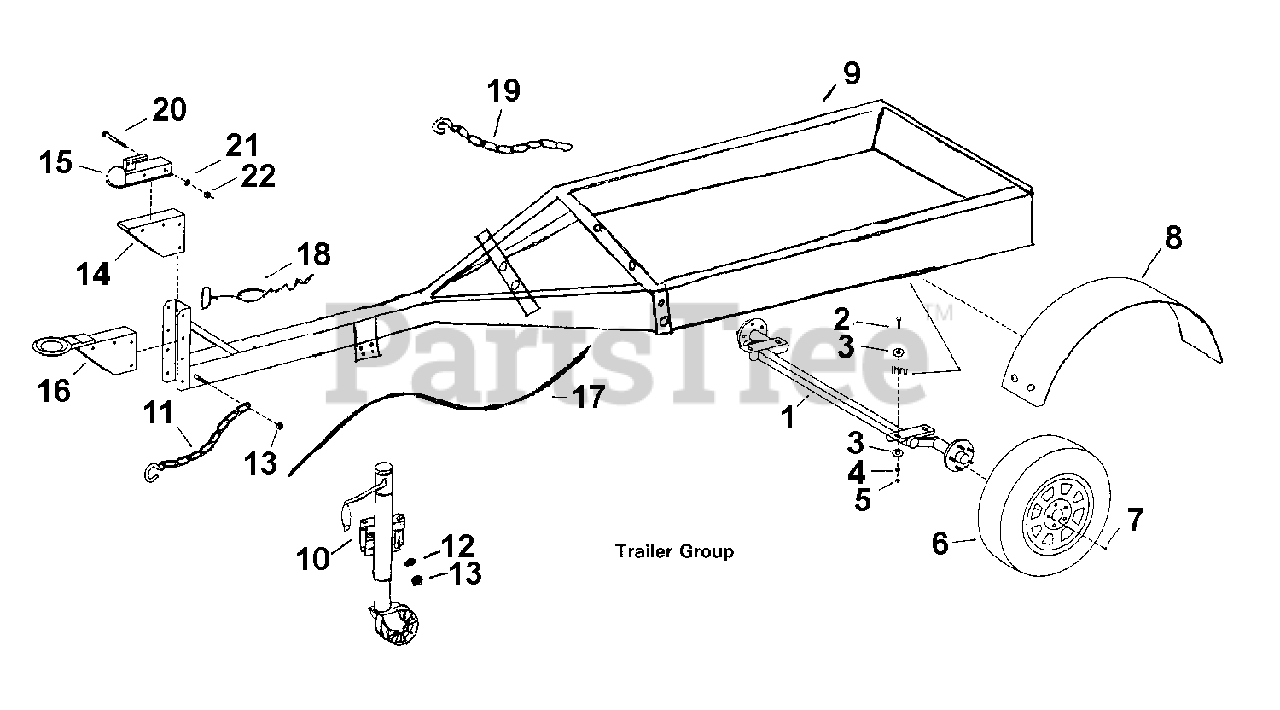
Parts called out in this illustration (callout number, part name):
1	Torflex Axle
2	1/2-13x1-1/4 Hex Bolt
3	1/2 Flat Washer
4	1/2 Lock Washer
5	1/2-13 Hex End Lock Nut
6	Tires 700x15
8	Fender R.H.
8	Fender L.H.
9	Trailer Frame
10	Jack, 2 Wheel
11	Chain, Safety w/1 S-Hook
12	3/8 Lock Washer
13	3/8-16 Hex Nut
15	Ball Hitch & Adapter 2-5/16
16	Pintle Ring (Optional)
17	Wiring Harness
18	Breakaway Switch
19	Chain, Nozzle Retainer 1/2x12"
20	1/2-13x3-1/2 Hex Bolt
21	1/2 Lock Washer
22	1/2 Lock Nut
